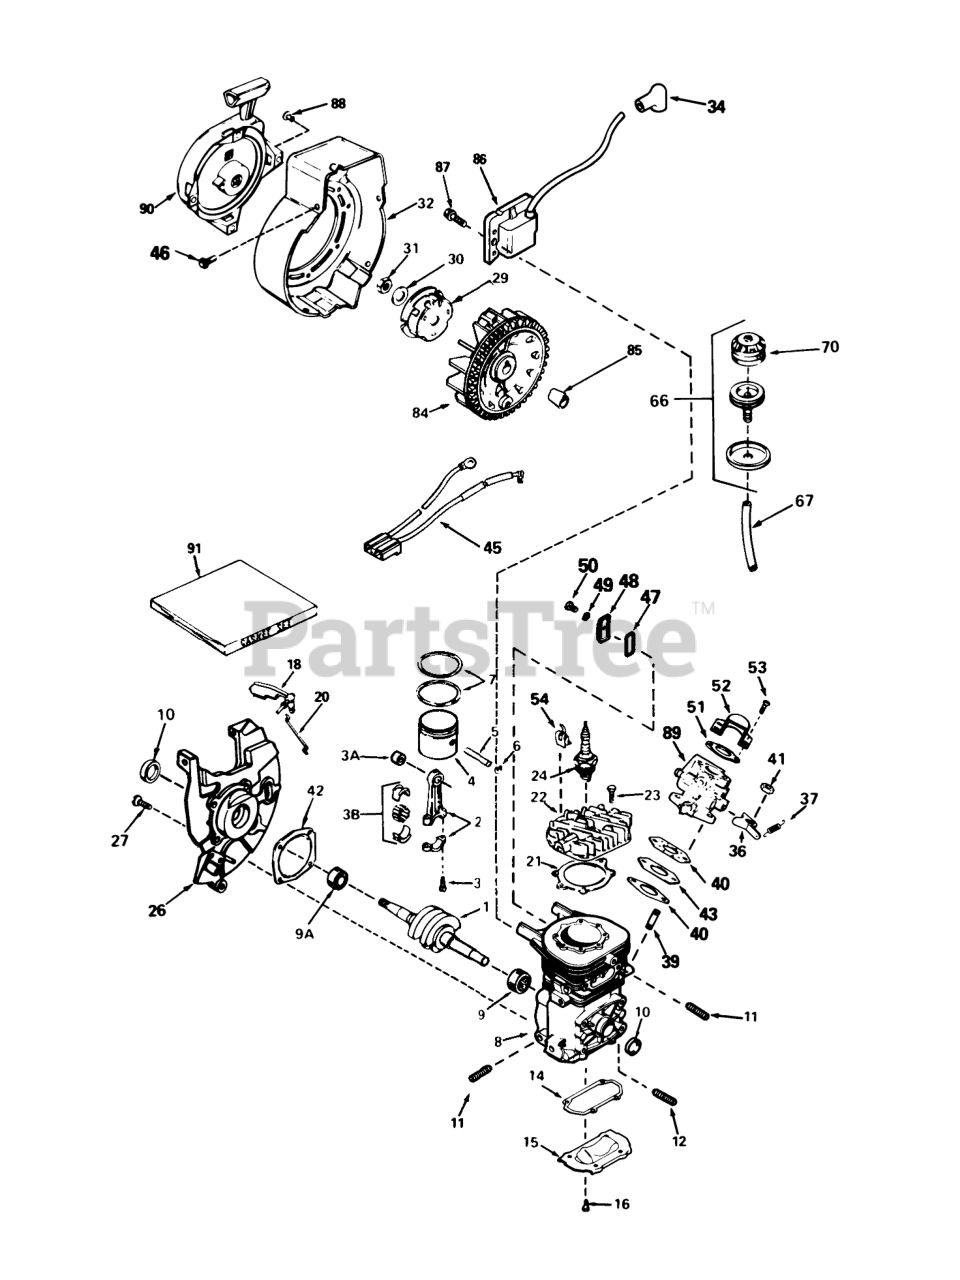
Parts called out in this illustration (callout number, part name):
1	Crankshaft
2	Rod Assembly-Connecting (Incl. Ref. #3, 3A & 3B)
3	Bolt-Rod, Connecting
3A	Bearing-Cartridge
3B	Needle Bearing and Liner Set (37 Needles)
4	Piston
5	Pin-Piston
6	Ring-Retaning
7	Ring Set
8	Block Assembly-Cylinder (Order short block if replace ment is required.)
9	Bearing-Cartridge
9A	Bearing-Ball
10	Seal-Oil
14	Cover
15	Plate-Cover
16	Screw (T-25, 10-24 x 1/2)
18	Vane-Air
20	Link-Governor
21	Gasket, Head
22	Head-Cylinder
23	Screw (T-30, 1/4-20 x 3/4)
24	Spark Plug-Resistor (R C J 8Y)
26	Base Assembly-Blower Housing (Incl. Ref. #10)
27	Screw (1/4-20x19/32)
29	Cup-Starter
30	Washer-Belleville
31	Nut-Flywheel
32	Housing-Blower
34	Cover-Spark Plug
36	Lever-Adjusting, Rpm
37	Spring-Governor
40	Gasket-Carburetor
41	Locknut
42	Gasket, Shroud Base
45	Harness-Wire
46	Screw-Hex, Hd.
47	Gasket-Cover
48	Comp. Release Cover
50	Screw (T-25, 10-24 x 1/2)
51	Gasket
52	Baffle-Carburetor
54	Clip
66	Primer Assembly (Incl. Ref. #70)
67	Line-Primer
70	Bulb-Primer
84	Flywheel
85	Blade (20 inch)
86	Solid State
87	Screw
88	Rivet-Pop (3/16" Dia.)(Can be purchased locally)
89	Carburetor (Incl. Ref. #40)
90	Starter-Rewind
91	Gasket Set
